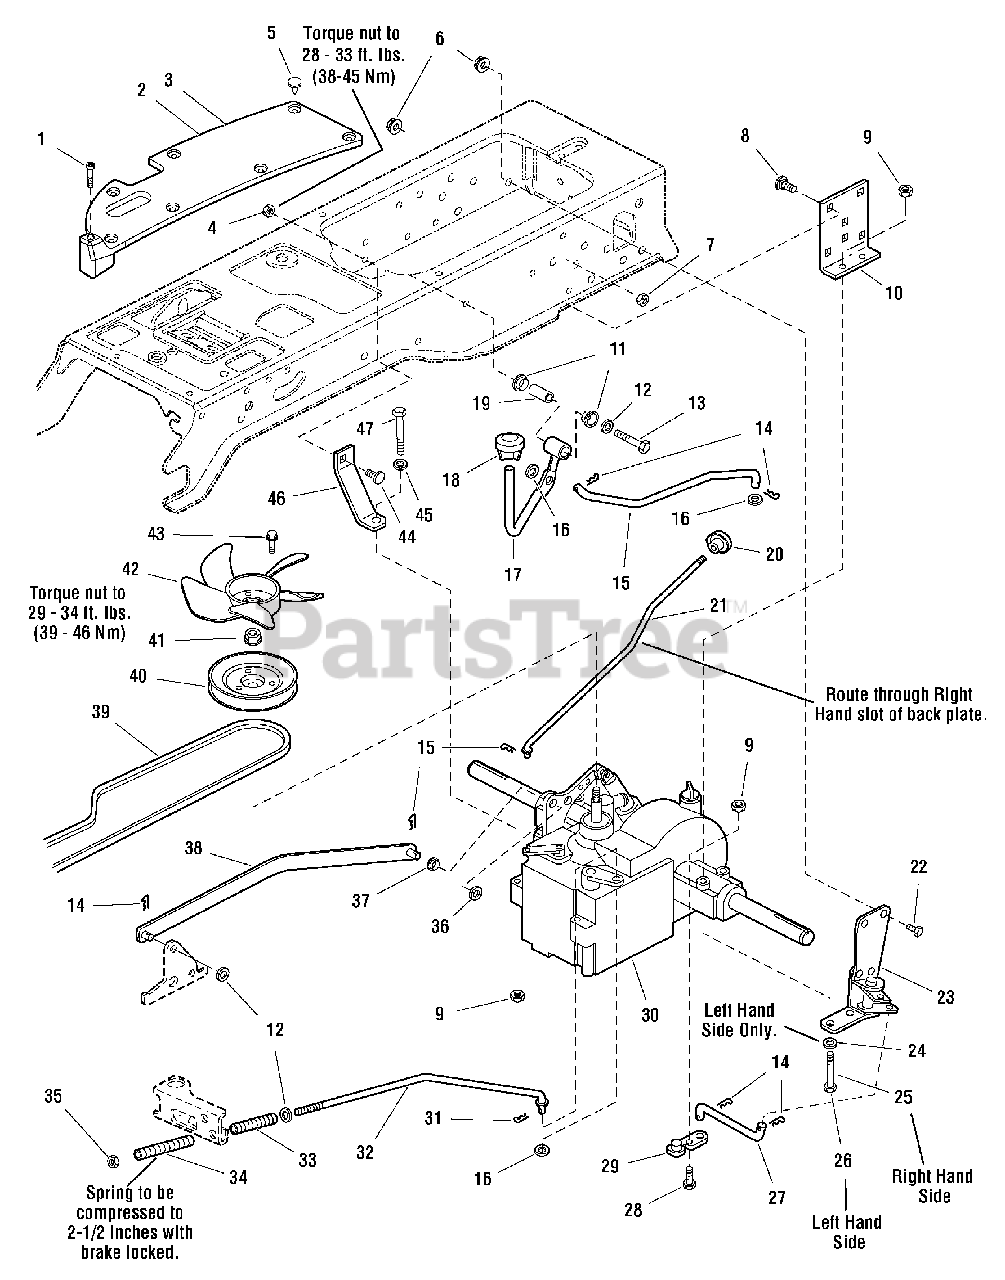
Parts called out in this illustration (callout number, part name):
1	SCREW, Pan Head Torx Taptite, 1/4-20 x 1-1/4
2	PAD, Footrest, LH, Differential Lock
3	PAD, Footrest, RH
4	NUT, Hex KEPS, 5/16-18
5	FASTENER, 11/16" Long, Stem Plastic
6	NUT, Hex Flange Whiz Lock, 3/8-16, Large
7	NUT, Hex KEPS, 3/8-16
8	CARRIAGE BOLT, 3/8-16 x 1
9	NUT, Hex Flagne ESNA, 5/16-18
11	BUSHING, 5/8 x 3/4 x 13/32, Powder Metal
12	WASHER, 3/8
13	CAPSCREW, Hex Head, 3/8-16 x 2-1/4
14	PIN, Quick
15	ROD, Differential Lock, 15-3/16 Long
16	WASHER, 7/16
17	ROD & TUBE ASSEMBLY, Differential Lock Pedal
18	KNOB, Hole, 1/2 x 1-3/4, 2-11/16 Long
19	SPACER, 25/64 x 5/8 x 1-1/2, Hardened
20	KNOB, 3 Sided Soft
21	ROD, Free Wheel, 18-3/16 Long
22	CAPSCREW, Hex Head, 3/8-16 x 1, Black
23	PIVOT ASSEMBLY, Differential Lock
24	WASHER, 5/16, Black
25	CAPSCREW, Hex Head, 5/16-18 x 2-3/4
26	CAPSCREW, Hex Head, 5/16-18 x 3
27	ROD, Differential Latch, 2 Bends, 6-3/16 Long
28	CAPSCREW, Hex Head, 5/16-18 x 1
29	ARM, Differential Lock
30	TRANSMISSION ASSEMBLY, K66 Transmission
31	PIN, Cotter, 3/4, Black
32	ROD, Brake, 17-27/64 Long
33	SPRING, Compression
34	SPRING, Compression
35	NUT, Hex Flange ESNA, 3/8-16
36	WASHER, 1/2
37	BEARING, 1/2 x 9/16 x 3/4, Nylon
38	ARM & WELD PINS ASSEMBLY, Control K66
40	PULLEY & HUB ASSEMBLY, Transmission
41	NUT, Hex Flange, M10-1.5, Nylon Insert
42	FAN, 5 Blades, 3 Holes
43	CAPSCREW, Hex Washer Head Taptite, 1/4-20 x 1-1/8
44	CARRIAGE BOLT, 5/16-18 x 1
45	WASHER, 5/16
46	STRAP, 4-1/4 Long
47	CAPSCREW, Hex Head, 5/16-18 x 2-1/2
